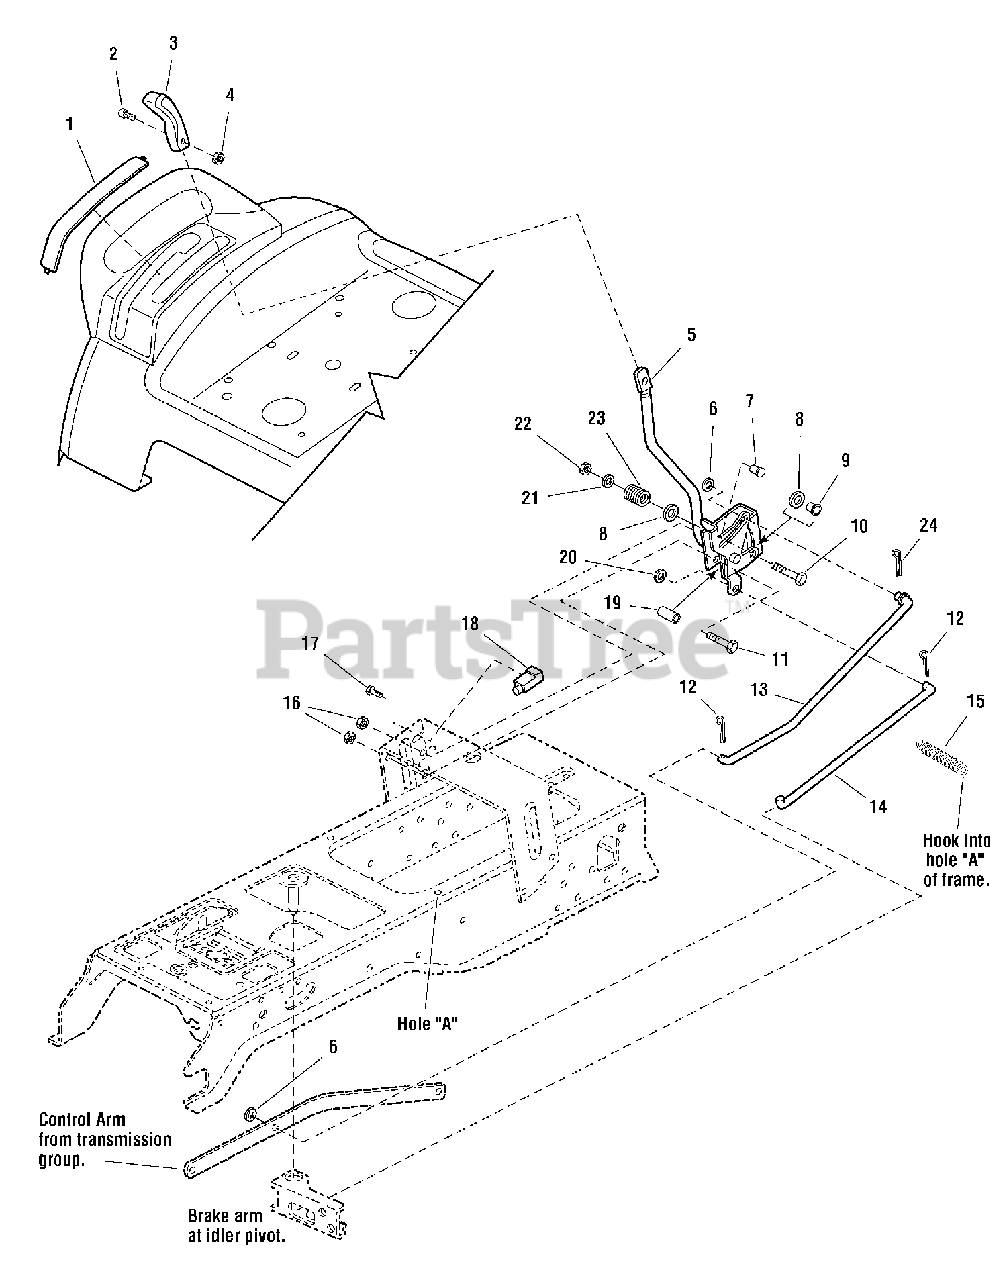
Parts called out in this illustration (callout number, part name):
1	COVER, w/Cruise Icon
2	SCREW, Torque Head Plus Socket Head, 1/4-20 x 7/8
3	KNOB, Cruise
4	NUT, Hex Lock ESNA Light, 1/4-20
5	LEVER & BRACKET ASSEMBLY, Cruise
6	WASHER, 3/8, Black
7	CARRIAGE BOLT, 5/16-18 x 3/4
8	WASHER, 1/2
9	SPACER, w/Flange, 11/32 x 15/32 x 3/4
10	CARRIAGE BOLT, 5/16-18 x 2-3/4
11	CARRIAGE BOLT, 5/16-18 x 2-1/4
12	PIN, Quick
13	ROD, Cruise
14	ROD, Return
15	SPRING, Cruise Return to Frame
16	NUT, Hex KEPS, 5/16-18
17	CAPSCREW, Hex Washer Head Plastite, 10-14 x 5/8
18	SWITCH, Push, Neutral Start, Gray
19	SPACER, 11/32 x 5/8 x 1-13/32
20	WASHER, 5/16, Black
21	WASHER, 5/16, Black
22	NUT, Hex Lock ESNA Light, 5/16-18
23	SPRING, Compression
24	PIN, Cotter
